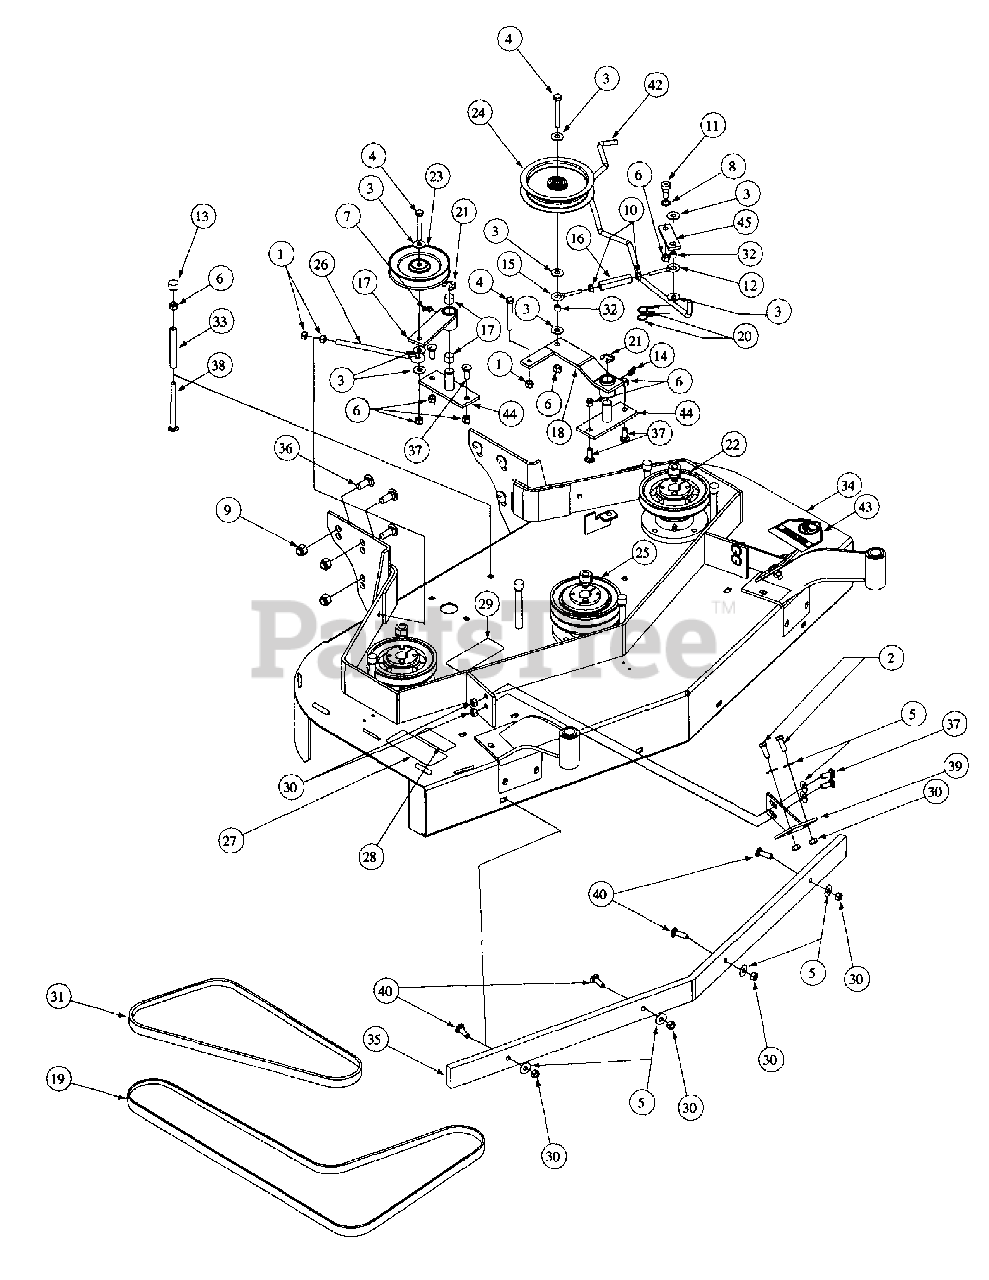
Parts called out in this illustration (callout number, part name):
1	Hex Nut, 3/8-16
2	Hex Cap Screw, 3/8-16, 1
3	Flat Washer, 3/8 Zinc
4	Hex Cap Screw, 3/8-16, 1
5	Flat Washer, 3/8 Zinc
6	Lock Nut, Nylon Insert, 3/8-16
7	Grease Fitting, 1/4-28, 90 degree
8	Shim Washer
9	Lock Nut, Nylon Insert, 1/2-13
10	Hex Nut, 5/16-18
11	Shoulder Bolt
12	Eye Bolt, Right Hand
13	Vinyl Cap
14	Grease Fitting, 1/4-28 x 3/16
15	Eye Bolt, Left Hand
16	Turnbuckle
17	Idler Arm "B"
18	Idler Arm "A"
19	Drive Belt
20	Hair Pin, 3/8"-1/2"
21	E-Ring
22	Deck Pulley
23	Idler Pulley
24	Idler Deck Take-up
25	Double Pulley
26	Rob Belt Tensioner
27	Decal Rotating Blade
28	Decal Warning Safety
29	Decal Warning Shield Missing
30	Lock Nut, Metal, 3/8-16
31	Drive Belt
32	Sieve Turnbuckle
33	Spacer Belt Guide
36	Carriage Bolt, 1/2-13 x 1-1/4
37	Carriage Bolt, 3/8-16 x 2
38	Carriage Bolt, 3/8-16 x 4-1/2
39	Caster Support Assembly
40	Carriage Screw, 3/8-16 x 1-1/4
42	Rod Clutch Link
43	Decal, Danger Hands and Feet
44	Idler Base
45	Clutch Link
